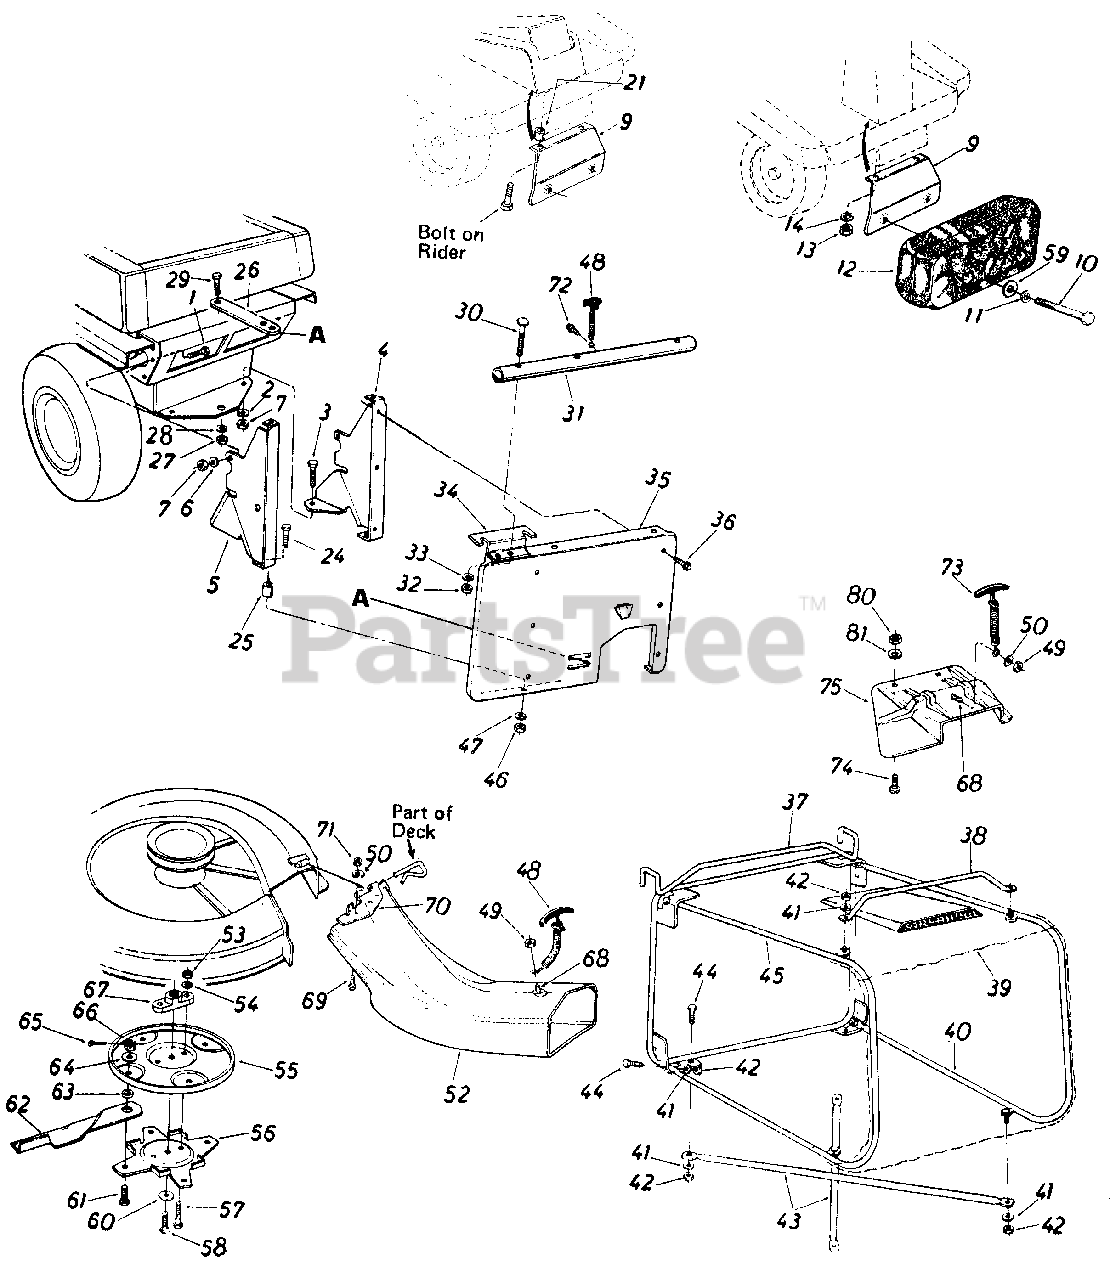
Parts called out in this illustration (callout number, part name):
1	Hex Bolt 5/16-18 x 1.0" Lg.
2	L.-Wash. 5/16" I.D.
3	Hex Bolt 5/16-18 x 1.0" Lg.'
4	Catcher Support Brkt R.H.
5	Catcher Support Brkt-L.H.
6	L.-Wash. 5/16" I.D.
7	Hex Nut 5/16-18 Thd.
9	Counterweight Support Brkt. Ass'y .
10	Hex Bolt 3/8-16 x 4.5" Lg.*
11	Belleville Wash. .40" I.D. x .88" O.D.
12	Counterweight 38 Ibs.
13	Hex Nut 5/16-18 Thd.
14	L.-Wash. 5/16" I.D.
21	Spacer .380" I.D. x 1.0" O.D. x .32" Lg.
24	Hex Bolt 5/16-18 x 1.50" Lg.
25	Spacer .380" I.D. x .47" O.D. x 1.0" Lg.
28	L.-Wash. 1/2" I.D."
29	Hex Bolt 1/2-20 x 1.0" Lg.*
30	Curved Carriage Bolt 5/16 18 x 1.75" Lg.
33	L.-Wash. 5/16" I.D.
34	Grass Catcher Support Plate
35	Rear Discharge Panel
36	Hex Wash. Hd. Self Tap. Scr. 1/4- 0 20 x .50" Lg.
37	Grass Catcher Frame Ass'y.
42	Hex L.-Nut 1/2-20 Thd
43	Bottom Cross Brace
44	Hex Bolt 1/4-20x .62" Lg.
47	L-Wash. 5/16" I.D.
48	Hook Latch Ass'y.
49	Hex L.-Nut 1/4-20Thd.
50	L.-Wash. 1/4" I.D.*
52	R.D. Banana Chute Ass'y.
53	Hex Nut 5/16-24 Thd.*
54	L.-Wash. 5/16" I.D.*
55	Upper 81ade Disc
58	Hex Bolt 3/8-24 x 1.0" Lg.
59	Fl.-Wash. .39" I.D. x 1.12" O.D.
60	Bell.-Wash. 39" I.D. x 1.38"
61	Shld. Bolt. .50" Dia. x .360 0 Spec.
62	30" Blade Tip
63	Spacer .505" I.D. x .75" O.D. x 1.25" Lg.
64	Fl.-Wash. .50" I.D. x 1.25" O.D.
65	Cotter Pin 3/32" Dia. x 1.0" Lg.*
66	Hex Slotted Nut 1/2-20 Thd.
67	Blade Adapter
68	Hex Bolt 1/4-20 x .50" Lg.
69	Truss Mach. Scr. 1/4-20 x .50" Lg. *
72	Hex AB 0 Tap Scr. 1/4 x .62" Lg.
73	Hook Latch Ass'y. 7" Lg.
74	Truss Mach. Scr. 1/4-20 x 50" Lg.
75	R D 0 Chute Extension
80	Hex L.-Nut 1/4-20 Thd.
81	Fl.-Wash. .281" I.D. x .50" O.D. x .063
